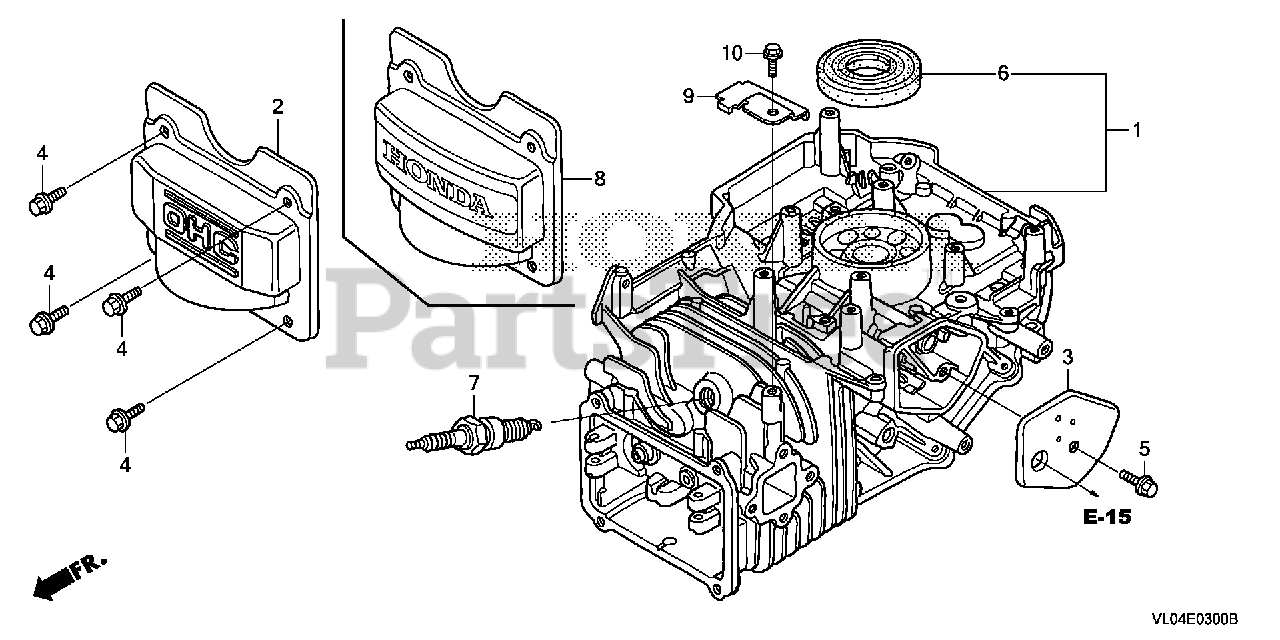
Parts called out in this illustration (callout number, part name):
1	CYLINDER ASSY.
3	COVER, BREATHER (BREATHER VALVE ASSY.)
4	BOLT, FLANGE (6X12) (CT200)
5	BOLT, FLANGE (6X14) (CT200)
6	OIL SEAL (25.4X62X6)
7	SPARK PLUG (BPR5ES) (NGK)
8	COVER, HEAD
9	BRACKET, REGULATOR
10	BOLT, FLANGE (6X14) (CT200)
